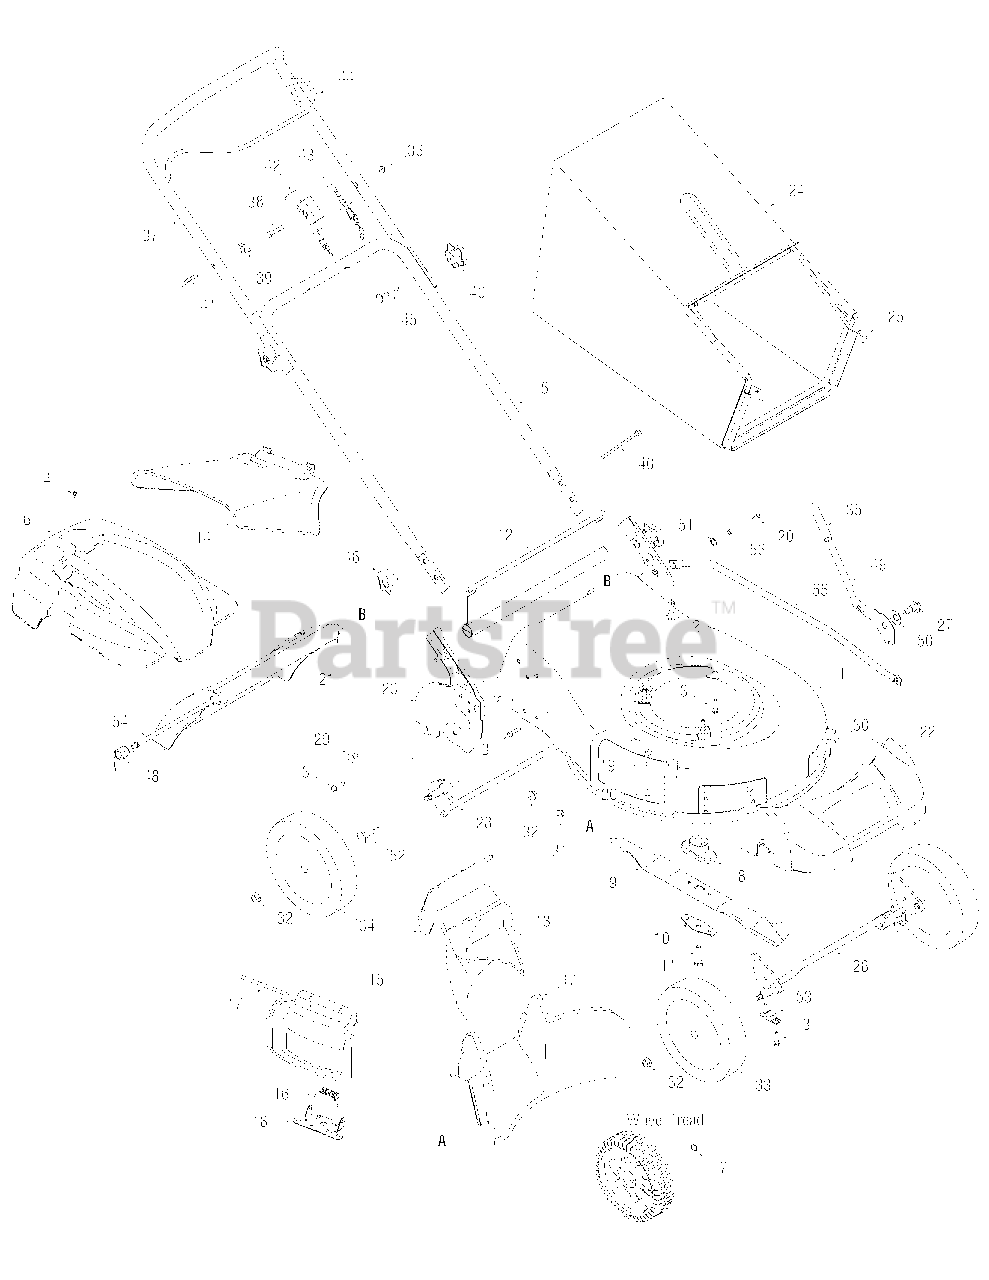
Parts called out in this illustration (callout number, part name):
3	Screw, 1/4-15 x 1.000
4	Screw, Machine, M4-.7 x 10.00
6	Engine Shroud
7	Washer, Wave, .510 x .750 x .017
8	Blade Adapter
9	Mulching Blade
10	Blade Bell Support
11	Screw, 3/8-24 x 1.50
12	Trailing Shield
13	Rear Mulch Plug
14	Side Discharge Chute
15	Mulch Plug (Incl. 16-18)
16	Torsion Spring
17	Hinge Pin
18	Chute Deflector Adapter
19	Beleville Washer
21	Rear Door
22	Front Cover
24	Grass Bag
27	Screw, Shoulder, .50 x .66
29	Bolt, Carriage, 5/16-18 x .62
30	Screw, 5/16-14 x .750
31	Nut, Flange Lock, 5/16-18
32	Nut, Flange Lock, 3/8-16
33	Front Wheel
34	Rear Wheel
35	Foam Grip
36	Nut, Flange Lock, 1/4-20
40	Cable Tie
41	Rope Guide
42	Choke Cable
43	Control Cable
45	Bolt Carriage, 5/16-18 x 2.0
46	Star Knob
47	Rear Baffle
48	Door Torsion Spring - RH
48	Door Torsion Spring - LH
49	Spring Lever
50	Washer, Bell, .510 x 1.14 x .040
51	Washer, Wave, .390 x .825 x .016
52	Screw, Shoulder, .500 Dia. X .434
53	Bushing, Lock, .505 Dia. X .62
54	Rear Door Pivot Rod
56	Spacer, 6.60mm ID x 9mm OD
